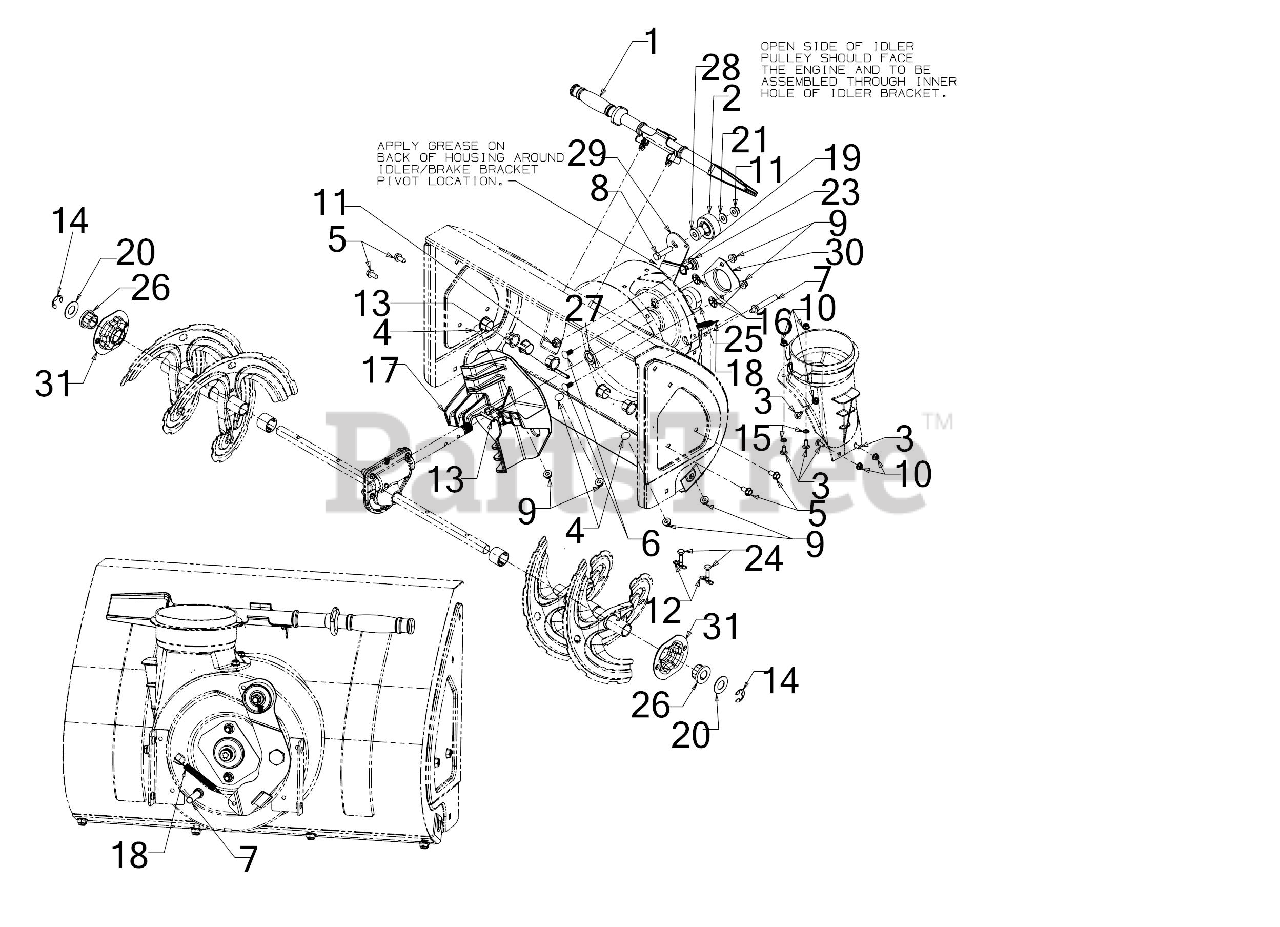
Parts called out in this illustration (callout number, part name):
1	CLEANOUT TOOL
2	IDLER PULLEY ASSEMBLY
3	CARRIAGE BOLT 1/4-20 x .62
4	CARRIAGE BOLT 5/16-18 x .62 GR5
5	SCREW 5/16-18 x .750
6	CARRIAGE BOLT 5/16-18 x .75
7	SCREW 5/16-18 x .4300
8	SCREW 3/8-16 x 1.50
9	FLANGE LOCK NUT 5/16-18
10	FLANGE LOCK NUT
12	BOW TIE COTTER PIN 1/4-5/16
13	SPIRAL PIN
14	E-RING
15	RETAINER-BOLT .25ID x .50OD
16	PUSH ON NUT
17	IMPELLER 9.486 DIA
18	EXTENSION SPRING
19	WAVE WASHER .660 ID X.88 OD x .010
20	FLAT WASHER .760ID X1.49OD x .06
21	FLAT WASHER
23	SHOULDER SCREW .625
24	SHEAR PIN .25 x 1.50 GR2
25	FLANGE BEARING
26	FLANGE BEARING
27	SPACER
28	SHOULDER SPACER .385 x .785 x .538
29	AUGER BRACKET W/BRAKE
30	BEARING HOUSIN 1.85 ID
